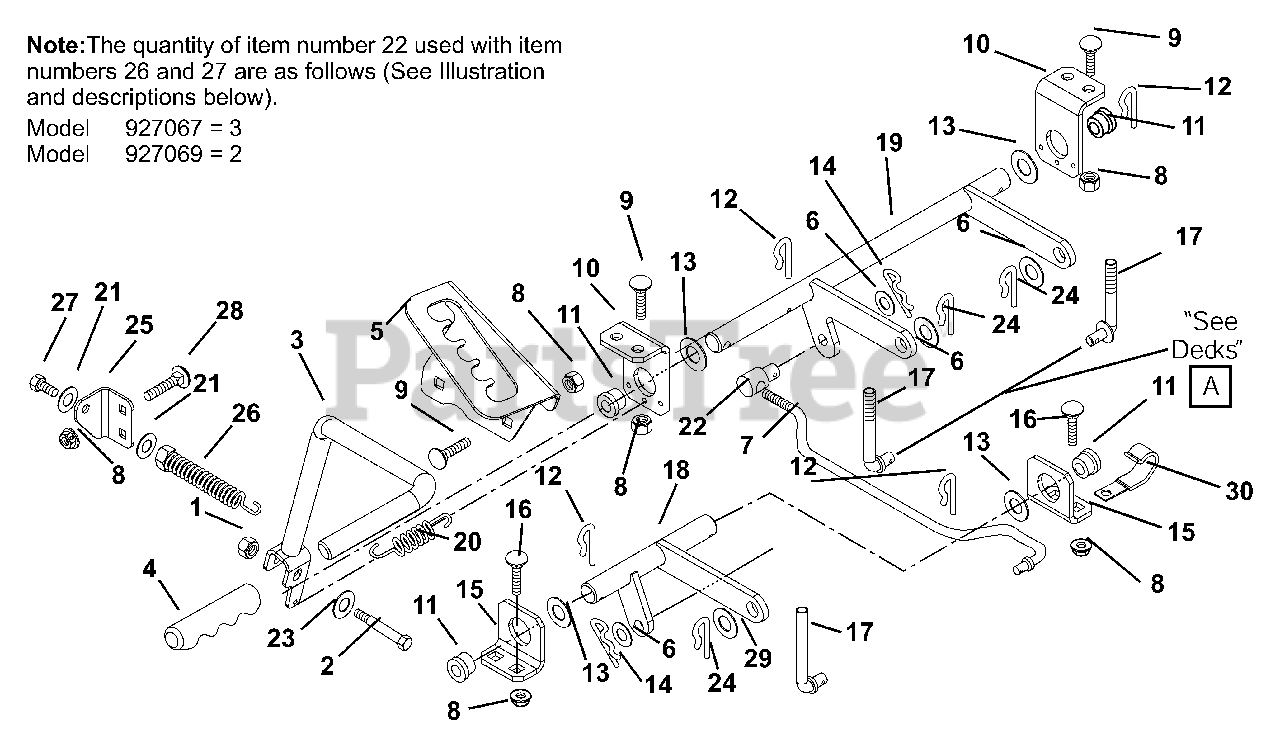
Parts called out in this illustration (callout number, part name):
1	NUT-LK-TOP-FLG .31-18 BLKZC
2	BOLT,SHLDR .38X1.25 .31-18 PLN
3	WLDM'T LIFT HANDLE
5	DETENT PLATE
6	WSHR-FL-STL.511X1.441X.125 YWZ
7	ROD, DECK LIFT
8	NUT-LK-TOP-FLG .38-16 BLKZC
9	BLT-RDHDSQNK .38-16X.75 G5BZ
10	BRACKET-HANGER
11	BSHG-FLG .750X1.000X.625X1.250
12	PIN, SPRING CLIP
13	WSHR-FL-STL .265X1.370X.179
14	PIN, HAIR, EXT - #16 YWZC
15	BRACKET-PIVOT
16	BLT-RDHDSQNK .38-16X1.00 G5BZ
17	LINK, LIFT
18	WMT, FRONT LIFT
19	WMT, REAR LIFT
20	SPRING, EXTENSION
21	WSHR,FLT .438X1.00X.160 ZCC
22	PIVOT, ROD
23	WSHR,FLT .438X1.00X.160 ZCC
24	CLIP, SPRING
25	BKT, SPRING ANCHOR
26	SG-TENS .195X1.147X5.50
27	@BLT-HEX .38-16X1.50 GR5 YWZC
28	BLT-RDHDSQNK .38-16X.75 G5BZ
29	@WSHR-FL-STL.563X1.38X.109YWZC
30	J-CLAMP
